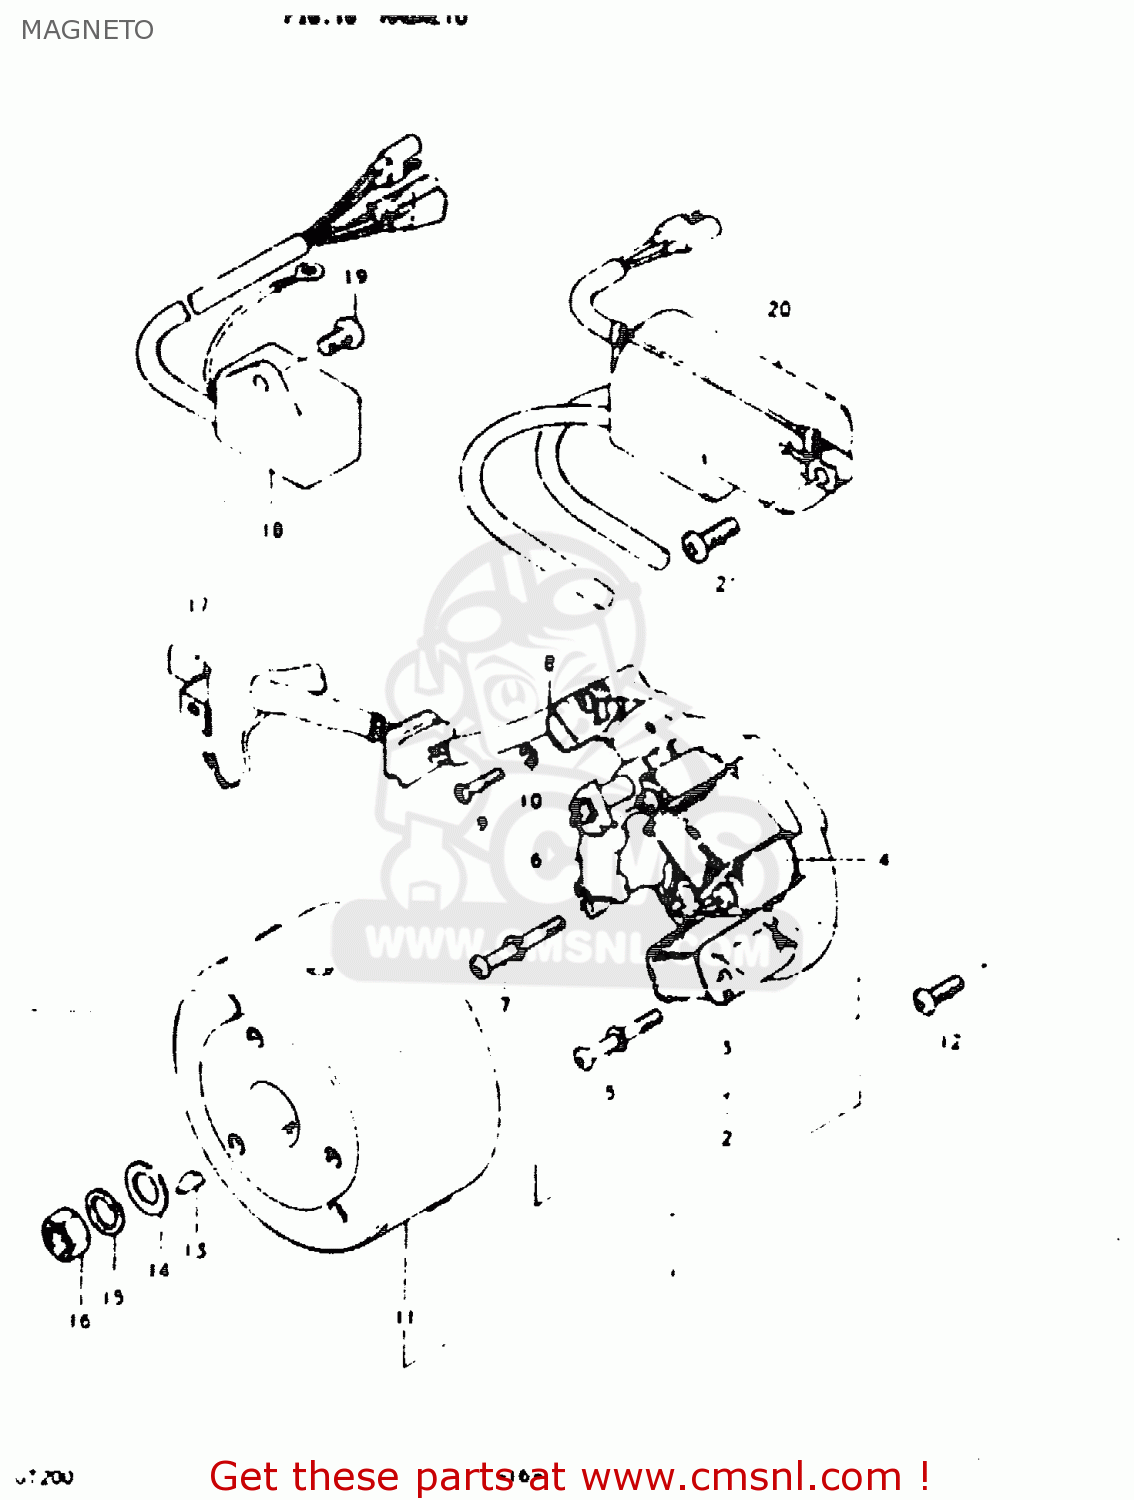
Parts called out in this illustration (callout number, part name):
1	MAGNETO ASSY
2	STATOR ASSY
3	COIL,LIGHTING(A)
4	COIL, LIGHTING B
5	SCREW
6	COIL, PRINAR,
7	SCREW
8	COIL,PULSER
9	SCREW
10	LOCK WASHER
11	ROTCH
12	SCREW
13	KEY
14	WASHER
15	WASHER,LOCK 12
16	NUT
17	CLAMP
18	C.D.I. UNIT ASSY
19	SCREW 6X12
20	COIL ASSY, IGNITION
21	SCREW
